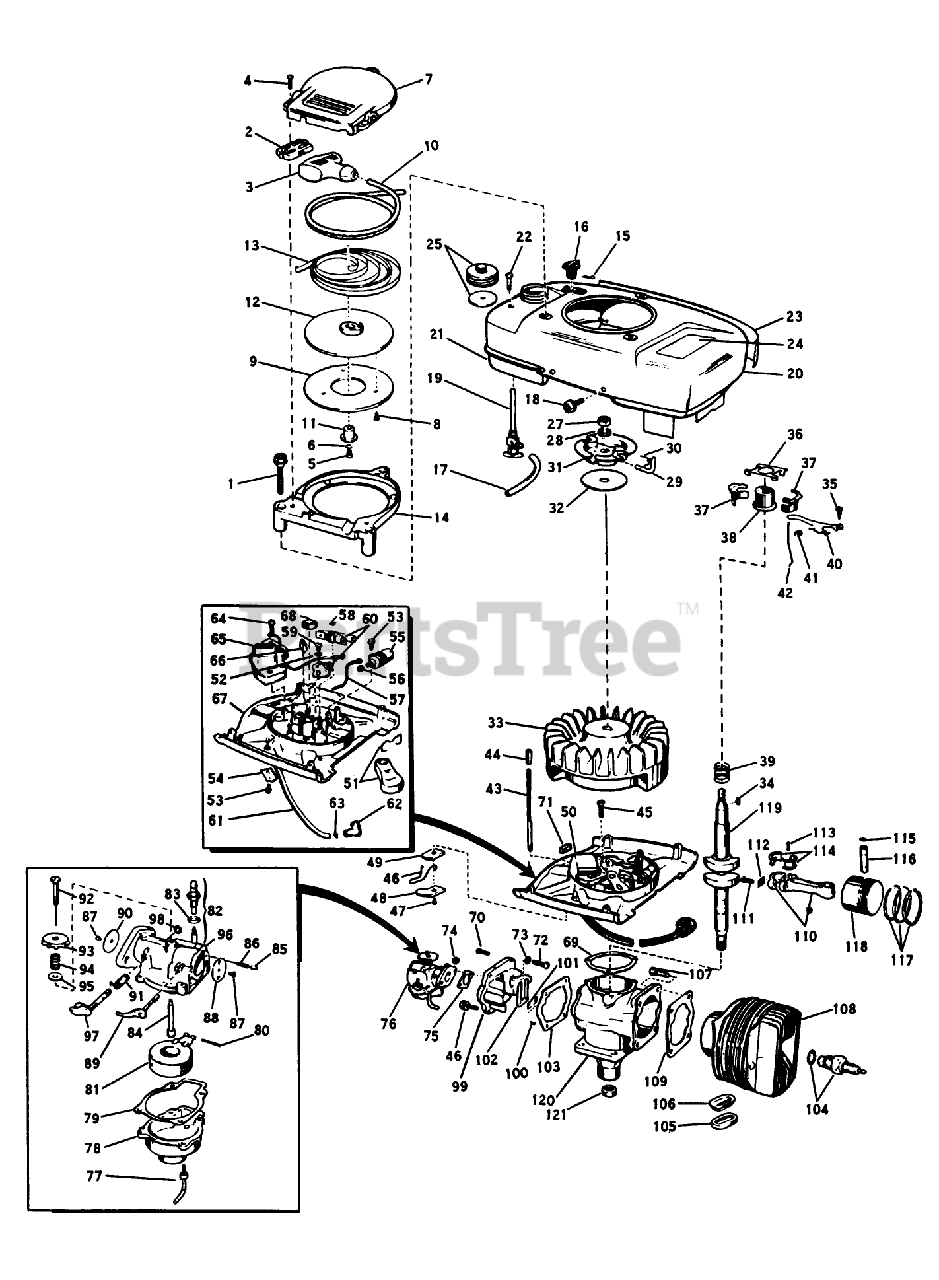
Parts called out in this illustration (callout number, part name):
9	Plate-Pulley
13	RECOIL SPRING
15	Cotter Pin-Choke Knob
16	KNOB, CHOKE BAR
18	SCREW S
19	VALVE&SCREEN SM
24	Decal-Instruction
29	PIN - STARTER
38	COLLAR S
40	GOVERNER LEVER AY
41	WEAR BLOCK S
42	GOVERNOR ROD S
46	SCREW S
47	Screw Shut-off Switch
60	BREAKER AY. S
62	Cover-Rubber
69	GASKET S
70	SCREW S
74	STOP NUT
75	GASKET S
81	Float and Arm Assembly (C-18AAR Engine)
83	WASHER
87	Screw-Choke Disc
88	Disc-Choke
89	CHOKE SHAFT&LVR AY
91	SPRING
92	NEEDLE AY. S
94	Spring-Ndl. Adj.
96	Carburetor Body (C-18AAR Engine)
101	PLATE-BACKUP, REED
104	Spark Plug
109	GASKET S
114	LINER ASM
115	RING-RETAINING
